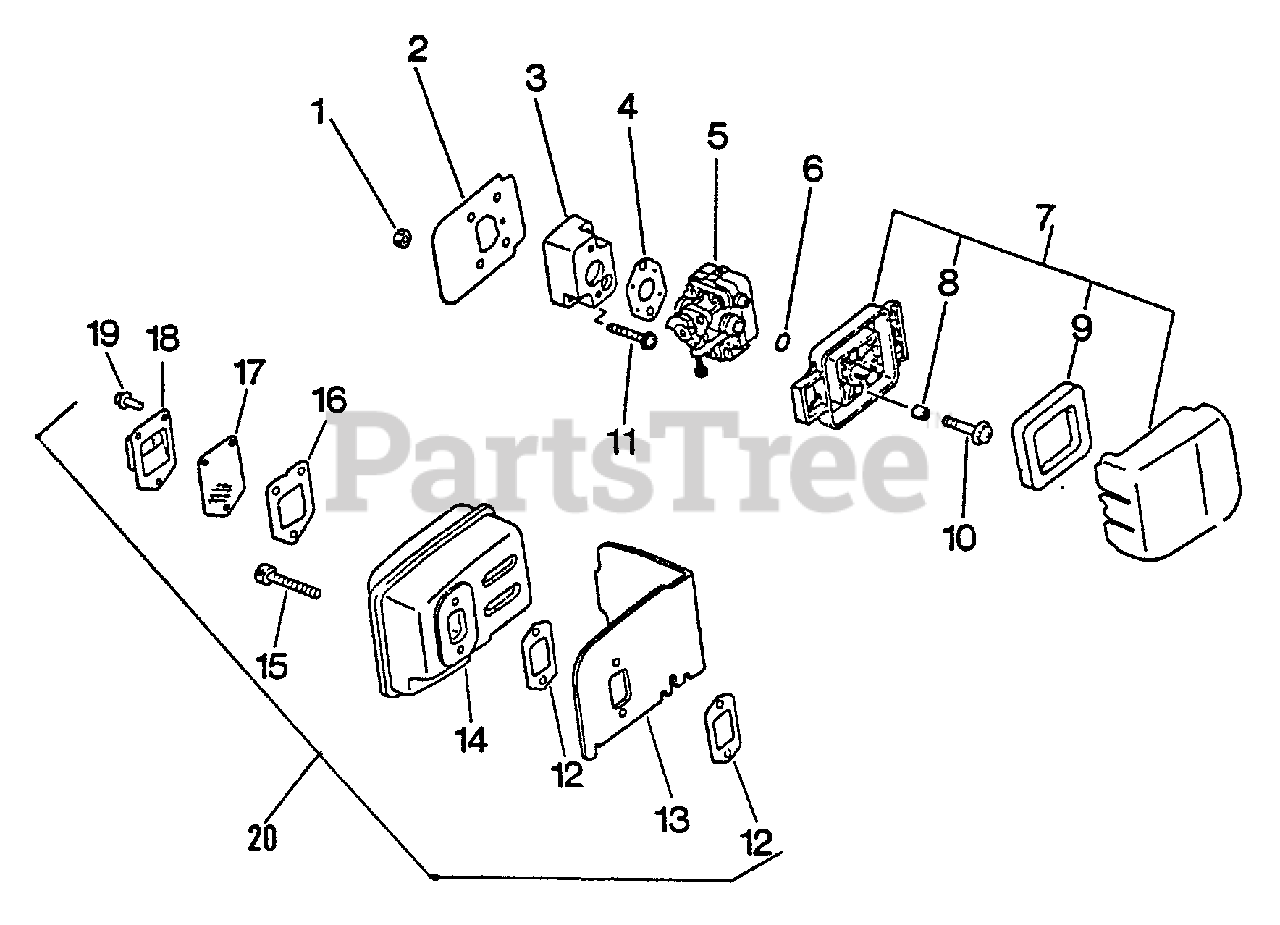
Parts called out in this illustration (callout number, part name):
1	NUT M5
2	HEAT SHIELD, INTAKE
3	INSULATOR, INTAKE
4	GASKET, INTAKE
5	CARBURETOR - WYL-11
6	O-RING 15
7	FILTER ASSY, AIR
8	SLEEVE
9	FILTER, AIR
10	SCREW 5×64
11	SCREW 5×22
12	GASKET, EXHAUST
13	COVER, EXHAUST
15	BOLT 5×55
16	GASKET, EXHAUST
17	SCREEN, SPARK ARRESTER
18	GUIDE, EXHAUST
19	SCREW 4×10
20	MUFFLER ASSY
